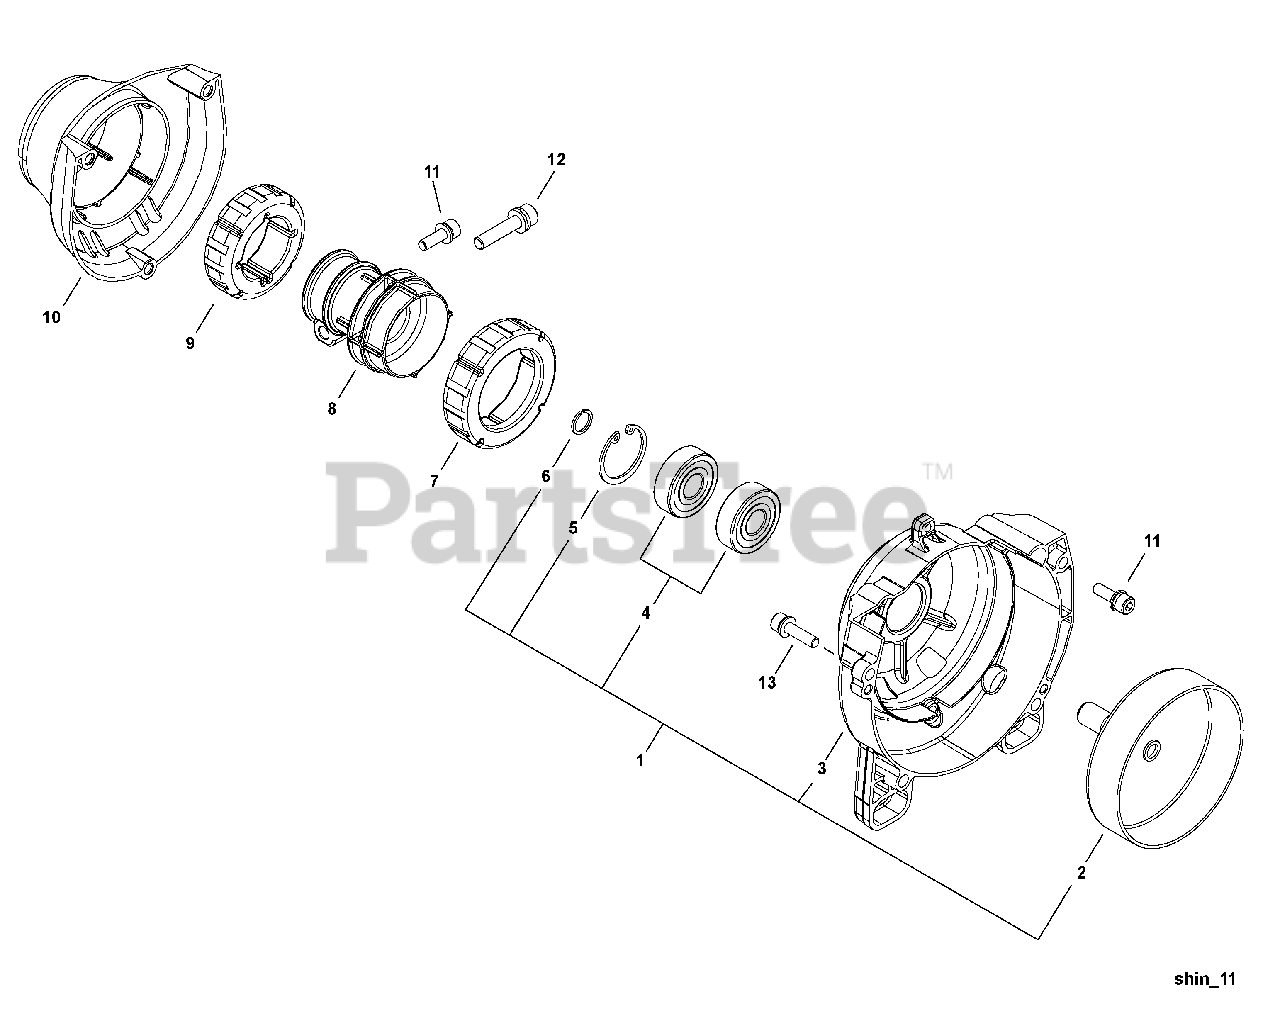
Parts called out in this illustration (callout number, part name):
1	FAN CASE ASSY
2	DRUM, CLUTCH
3	CASE, FAN
4	BEARING, BALL - 6001DDUC3
5	RING, RETAINING - 28
6	RING, RETAINING
7	CUSHION - REAR
8	CUSHION
9	CUSHION - FRONT
10	COVER, CUSHION
11	SCREW - 5X16
12	SCREW - 6X28
13	SCREW - 5X20
